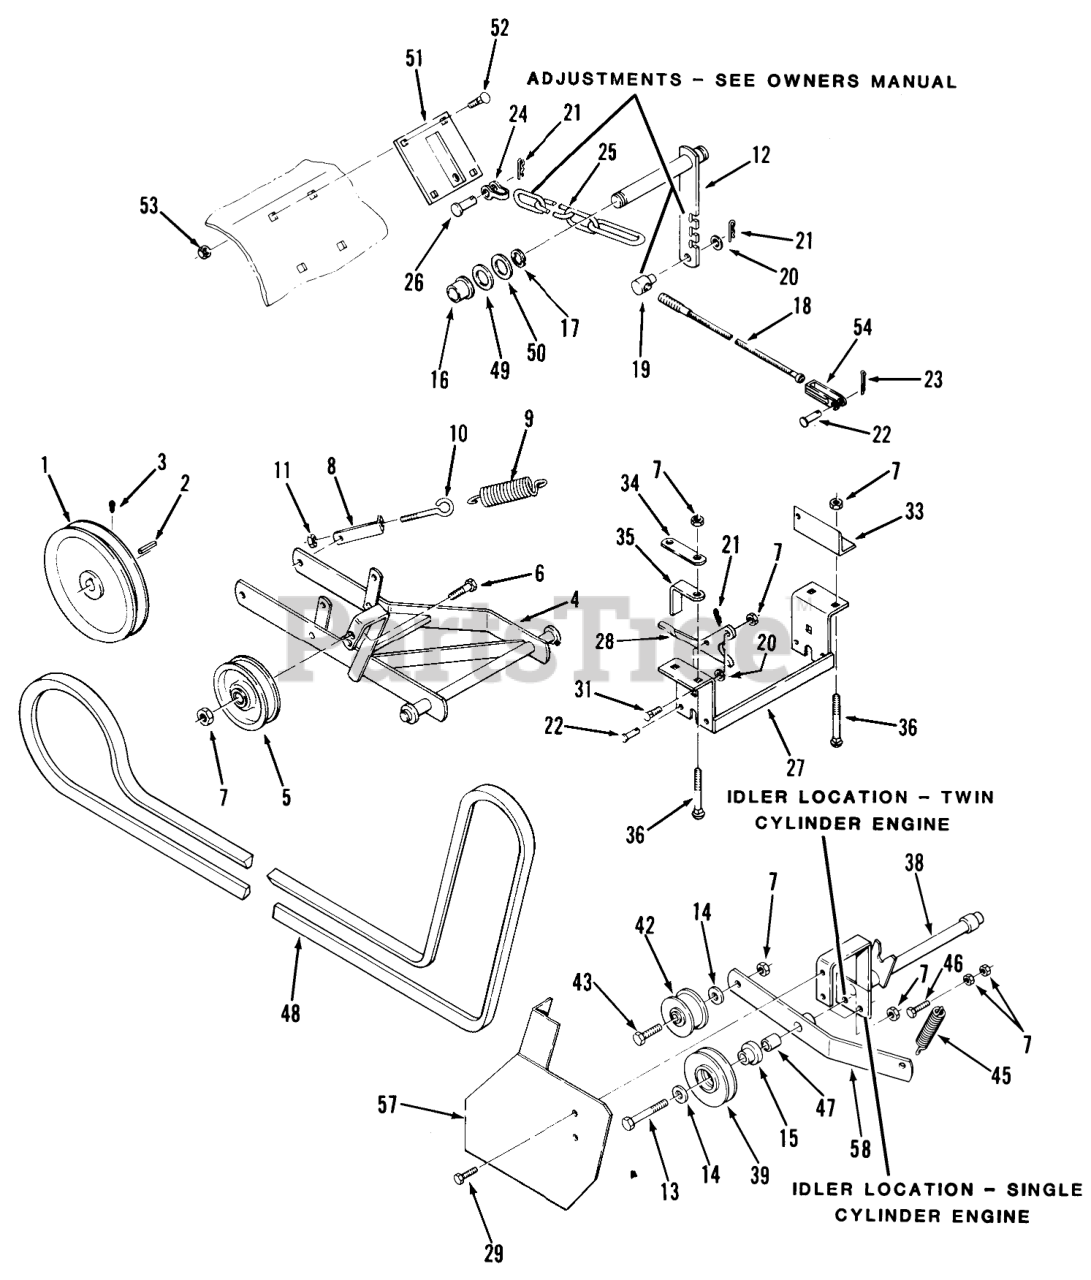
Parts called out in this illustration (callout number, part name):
1	Pulley
2	KEY-STRAIGHT
3	Set Screw
4	Hitch
5	Flat Idler
6	Bolt
7	Nut
8	Bracket-Spring
9	SPRING
10	EYEBOLT
11	NUT
12	ASSY LEVER R
13	Bolt
14	Washer
15	Spacer
16	BUSHING-BRONZE
17	E-RING
18	CABLE
19	TRUNNION-CLUTCH ROD
20	Washer
21	Hairpin
22	Pin
23	Cotter Pin
24	Clevis
25	CHAIN LIFT
26	Clevis Pin
27	Bracket
28	PLATE-LATCHING
29	Bolt
31	Bolt
33	LINK-BRACKET R
34	BRACKET-REAR LINK MOUNTING
35	SPACER-BRACKET
36	Bolt-Carriage
38	ASSY SUPPORT R
39	Pulley-V
42	IDLER PULLEY
43	BOLT
45	SPRING-BRAKE
46	Bolt
47	SPACER
48	V-BELT
49	WASHER
50	WASHER-SHIM
51	Lift Plate
52	Bolt
53	Nut
54	CLEVIS-SHORT
57	ASM: FRONT IDLER R
58	Arm-Idler
